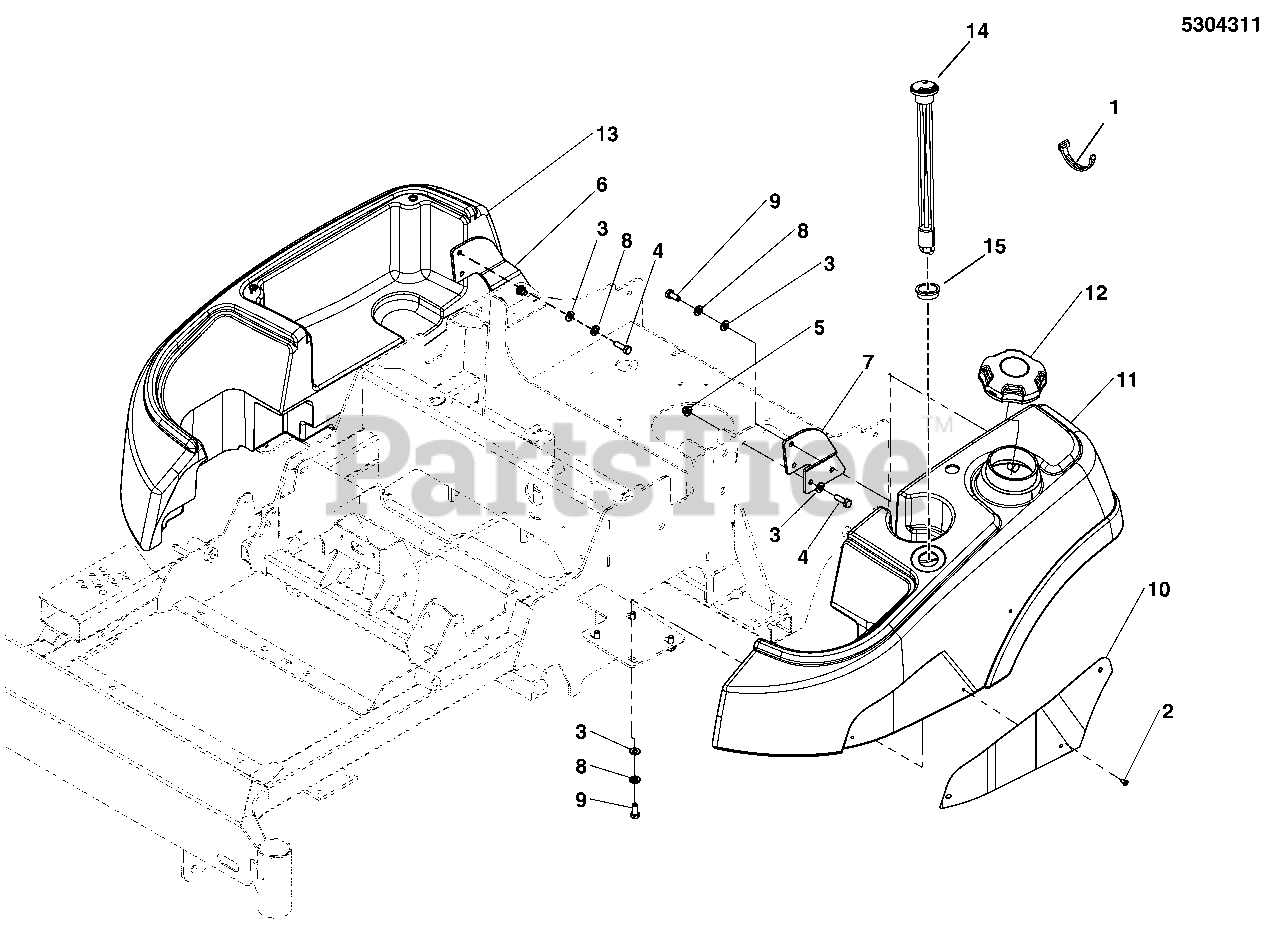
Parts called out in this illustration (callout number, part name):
1	TIE, SELF-LOCKING, 8"
2	SCREW, #10-24 X 3/8 ALLEN BHBZ
3	WASHER, 5/16 SAE
4	BOLT, 5/16-18 X 1 GD5 YZ
5	NUT, 5/16-18 HEX NYLOCK FLANGE
6	PLATE, FUEL TANK MOUNT - REAR, RH - RED
7	PLATE, FUEL TANK MOUNT - REAR, LH - RED
8	WASHER, 5/16 LOCK YZ
9	BOLT, 5/16-18 X 3/4 GD5
10	PLATE,FUEL TANK BADGE
11	TANK, FUEL, LH
12	FUEL CAP, 3-1/2", MANAGED VENT OUT, 12"
13	TANK, FENDER, CONZ, RH
14	GAUGE, FUEL LEVEL, 9.0"
15	GROMMET, FUEL GAUGE
